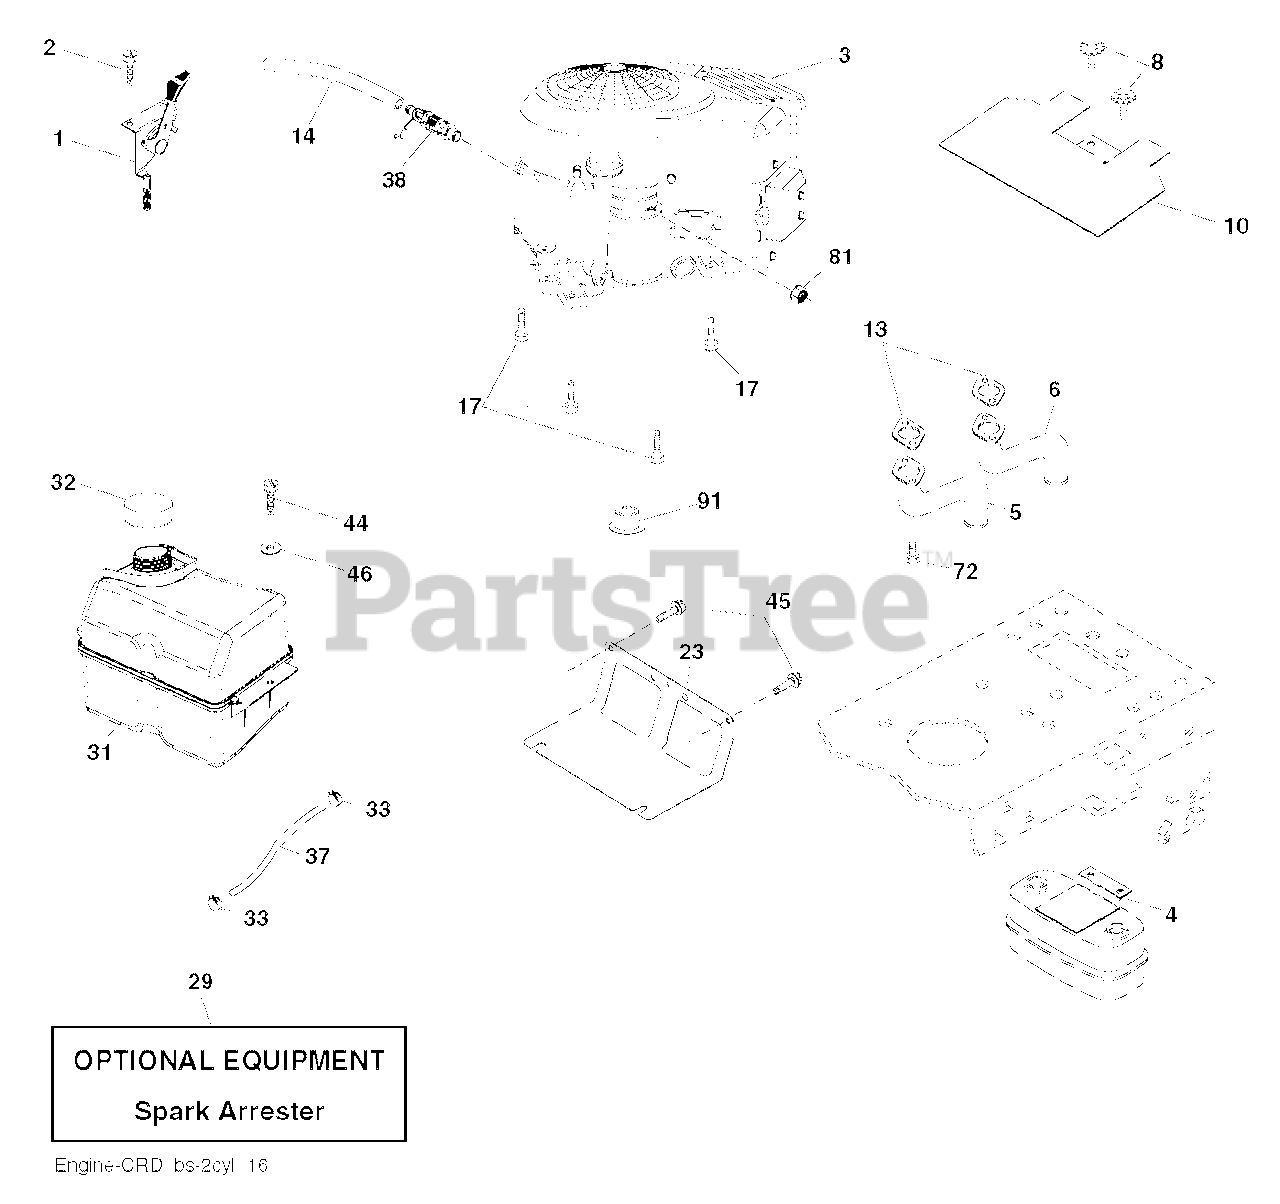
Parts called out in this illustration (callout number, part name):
1	CONTROL.TH/CK.COBRA.B&S.TWN.
2	SCREW.#10 X 0.750.BOS
4	MUFFLER.TWIN.CYL.LOW.TONE
5	RP.EXHAUST.TUBE.LH.BS/TWIN
6	EXHAUST.TUBE.RH.BS/TWIN
8	BOLT, 5/16-18 X 1 3/4
10	SHIELD.HEAT.MUFFLER
13	GASKET.MUFFLER
14	TUBE, DRAIN OIL ASM.
17	SCREW.3/8-16
23	SHIELD.BROWNING.DBR.GUARD
29	KIT.SPARK ARRESTOR 794945 B&S
31	TANK.ASM.FUEL.FR.2.5GA.
32	CAP ASM.FUEL.2.25"FR.
33	HOSE CLAMP
37	LINE.FUEL.20
38	VALUE.OIL.DRAIN
44	SCREW HEXWSHR 1/4-20X3/4
45	SCREW, 3/8-16X3/4
72	SCREW.SOCKET.HEAD.5/16-18
81	NUT
91	BUSHING.1.375OD
